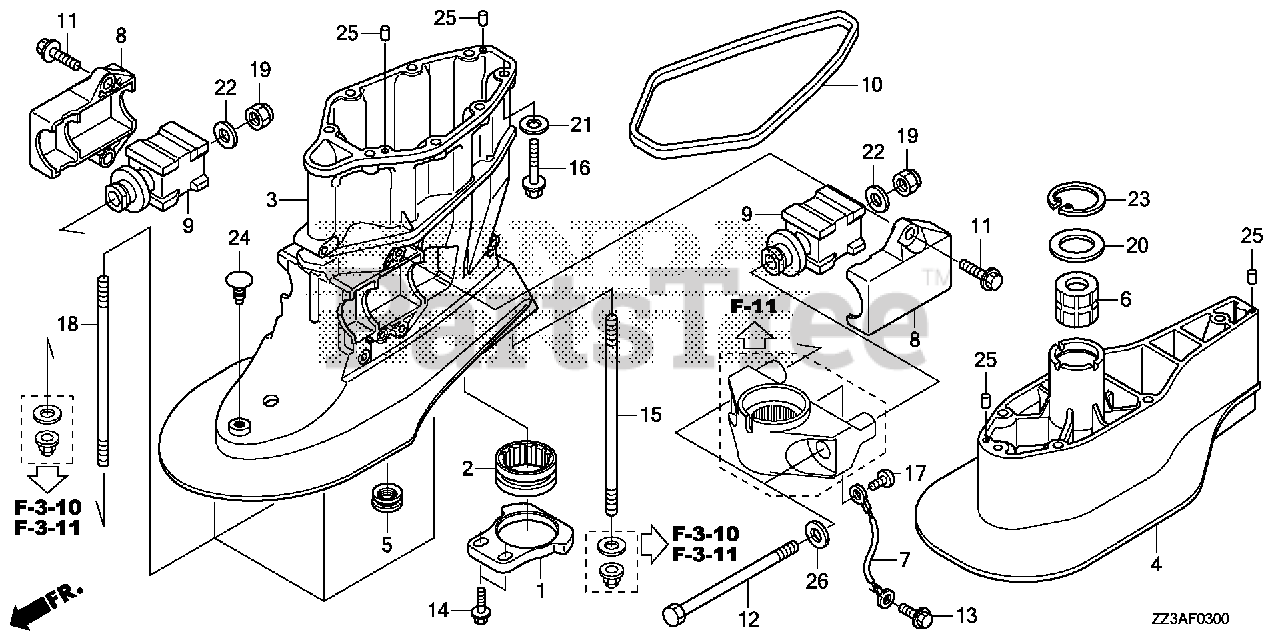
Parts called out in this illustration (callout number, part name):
1	HOLDER, EX. PIPE GROMMET
2	GROMMET, EX. PIPE
3	CASE, EXTENSION *NHB14M* (AQUA MARINE SILVER METALLIC)
4	SEPARATOR, EXTENSION *NHB14M* (XL) (AQUA MARINE SILVER METALLIC)
5	GROMMET, EXTENSION CASE
6	BUSH, VERTICAL SHAFT
7	WIRE, LEAD (1.5X116MM)
8	HOUSING, MOUNTING (LOWER)
9	MOUNT, RUBBER (LOWER)
10	SEAL B, COVER (LOWER)
11	BOLT, FLANGE (8X25)
12	BOLT, HEX. (12X186)
13	BOLT, FLANGE (6X12)
14	BOLT, FLANGE (6X20)
15	BOLT, STUD (10X202)
16	BOLT, FLANGE (8X35)
17	SCREW, PAN (6X8)
18	BOLT, STUD (10X164)
19	NUT, SELF-LOCK (12MM)
20	WASHER (26MM)
21	WASHER, PLAIN (8MM)
22	WASHER, PLAIN (12MM)
23	CIRCLIP (INNER) (40)
24	CLIP (7MM)
25	PIN, DOWEL (6X10)
26	WASHER, PLAIN (12MM)
